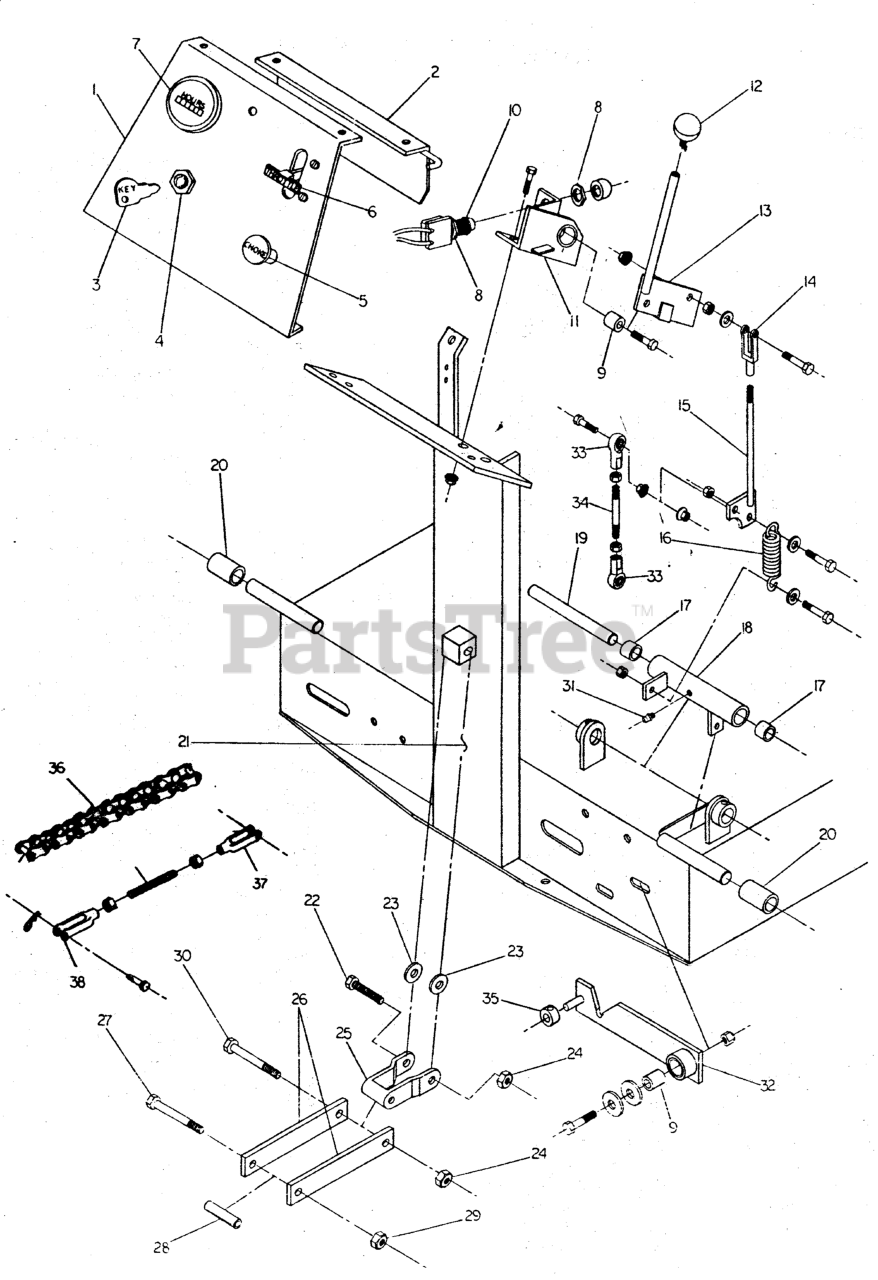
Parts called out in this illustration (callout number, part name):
1	Control Panel
2	Back Plate
3	Ignition Key
4	SWITCH, Ignition
4	SWITCH, IGNITION, 6 POST
5	CABLE, CHOKE CONTROL, 45
6	CABLE, Throttle, 31"
6	CABLE, Throttle, 38"
7	HOUR METER
8	Brass Nut
9	SPACER, .32 x .75 x 1.06
10	Parking Brake Switch Assembly
11	Parking Brake Mount
12	Black Knob
13	Parking Brake Handle
14	CLEVIS, 5/16-24, Plastic
15	Brake Rod
16	SPRING, Extension
17	BUSHING
18	Parking Brake Bell Crank
19	3/4" Shaft
20	5/8 Hose
21	Engine Deck
22	BOLT, 5/16-18 x 2
23	WASHER, 5/16" SAE
24	NUT, 5/16-18 Hex Nylon Lock
25	Coupler Link
26	Electric Lift Linkage
27	BOLT, 3/8-16 X 2-1/4" GD5 CZ
28	Actuator Spacer
29	NUT, 3/8-16 HEX NYLON LOCK
30	BOLT, 5/16-18 x 2-1/4
31	GREASE FITTING
32	NEUTRAL LOCK LEVER, Complete
33	BALL JOINT 5/16-24 RH FEMALE BRONZE RACE
34	Linkage Rod
35	COLLAR, 5/16" Set
36	Plated #60 Connector
37	STUD, 5/16-24 x 3"
38	CLEVIS, 5/16-24, Plastic
